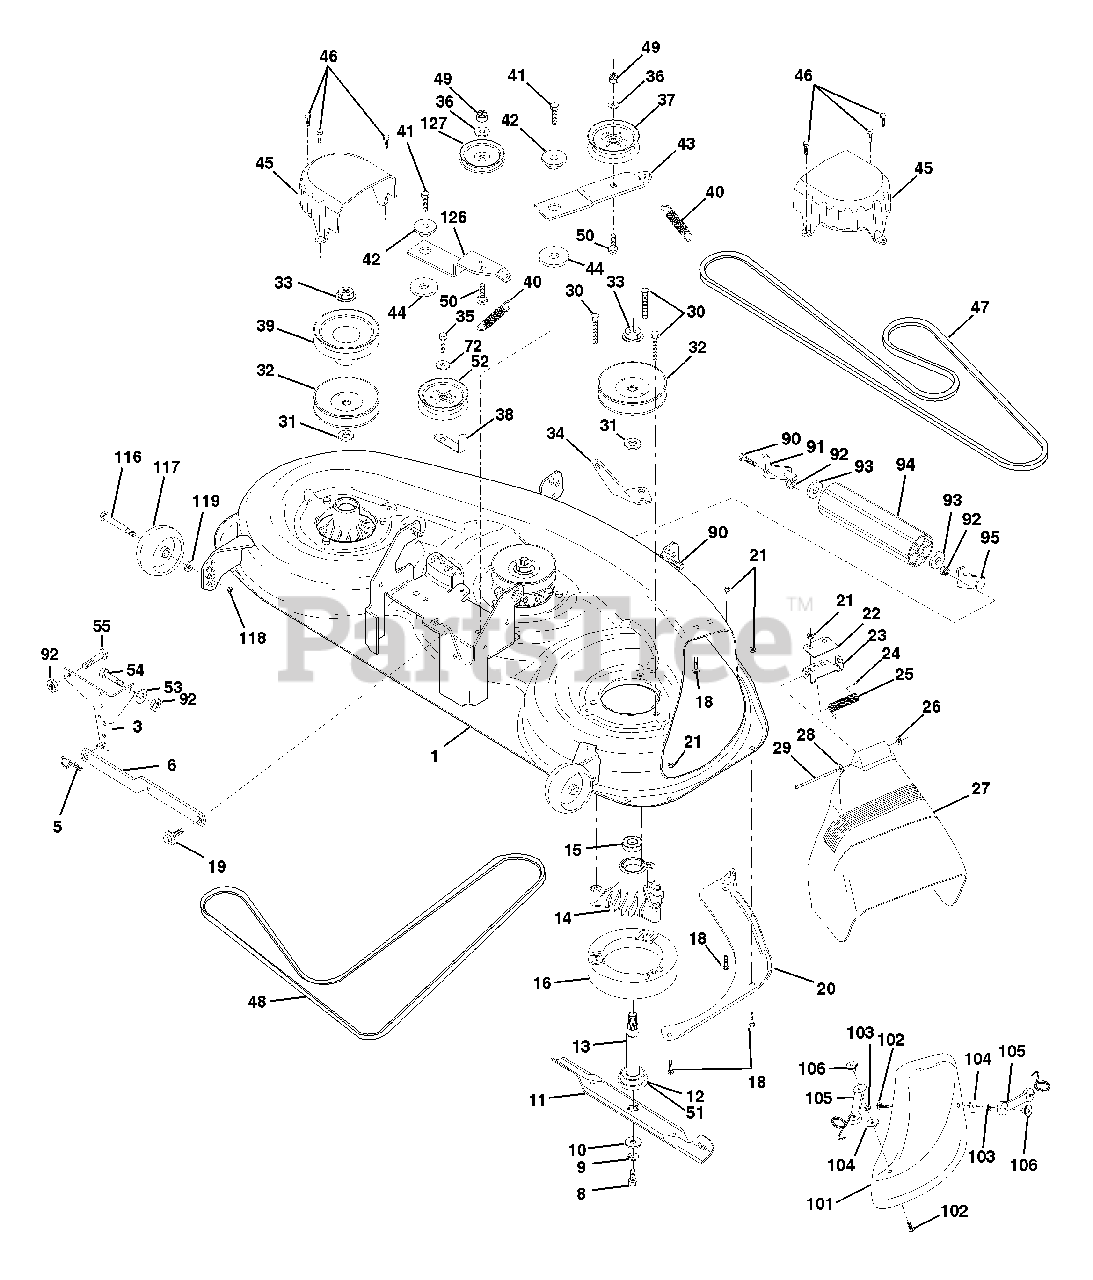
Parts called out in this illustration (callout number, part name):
1	Deck Asm., Mower 46"
3	Bracket Asm., Sway Bar
5	Retainer Spring
6	Arm, Suspension, Rear (Sway Bar)
8	Bolt, Patched 3/8-24 x 1-1/4 Gr. 8
9	Washer, Lock Hvy., Unplated 3/8
10	Washer, Hard Blade, Mower Vented
11	Blade, 46" Mower Deck
12	Bearing, Ball, Mandrel #6204
13	Shaft Asm. w/Lower Bearing
14	Housing, Mandrel
15	Bearing, Ball, Mandrel
16	Stripper, Mower Round
18	Bolt, Carriage 5/16-18 x 5/8
19	Bolt, Hex Head, Shoulder 5/16-18
20	Baffle, Vortex Mower 46"
21	Nut, Crownlock 5/16-18 UNC
22	Stiffener, Bracket
23	Bracket, Deflector
24	Cap, Sleeve
25	Spring, Torsion, Deflector
27	Shield, Deflector Mower
28	Washer 11/32 x 5/8 x 16 Ga.
29	Rod, Hinge
30	Screw, Hex Head, Thdroll
31	Washer, Spacer Mower Vented
32	Pulley, Mandrel
33	Nut, Flg. Top Lock Cntr. 9/16
34	Anchor, Spring Deck 46"
35	Screw, Thdroll 3/8-16 x 1-3/4 Tytt
36	Washer 13/32 x 13/16 x 16 Ga.
37	Pulley, Idler, Flat
38	Keeper, Belt, Idler
39	Pulley, Idler, Driven
40	Spring, Secondary 44/46/50 Vent
41	Screw, Thdroll 3/8-16 x 1-1/4 Tytt
42	Spacer, Retainer
43	Arm, Idler Secondary
44	Washer, Hardened
45	Cover, Mandrel Deck
46	Screw, Thdroll. 1/4-20 x 5/8
47	V-Belt, Mower, Secondary
48	V-Belt, Mower, Primary
49	Nut, Crownlock 3/8-16 UNC
50	Bolt, Carriage 3/8-16 x 1-1/2 Gr. 5
51	Washer, Felt
52	Pulley Idler Flat 46 Pri. Drive
53	Washer 13/32 x 13/16 x 12 Ga.
54	Bolt Fin Hex 3/8-16unc x 1 Gr. 5
55	Bolt Rdhd Sqnk 3/8-16unc x 1
72	Washer 13/32 x 1 x 16 Ga.
90	Bolt, Fin, Hex 3/8-16 UNC x 1
91	Bracket, Asm Noseroller, LH
92	Nut, Lock, Hex w/Ins 3/8-16UNC
93	Washer 17/32 x 7/8 x 16 Ga.
94	Roller, Nose 38 & 42
95	Bracket, asm Noseroller RH
101	Cover, Mulching
102	Screw
103	Washer, Lock #10
105	Latch Asm. Bagger
106	Nut, Weld
116	Bolt, Shoulder
117	Gauge Wheel
118	Nut, Centerlock 3/8-16 UNC
119	Washer 3/8 x 7/8 x 14 Ga.
126	Arm, Idler, Primary Deck 46"
127	Pulley, Idler, V-Groove Dim. 4.25
